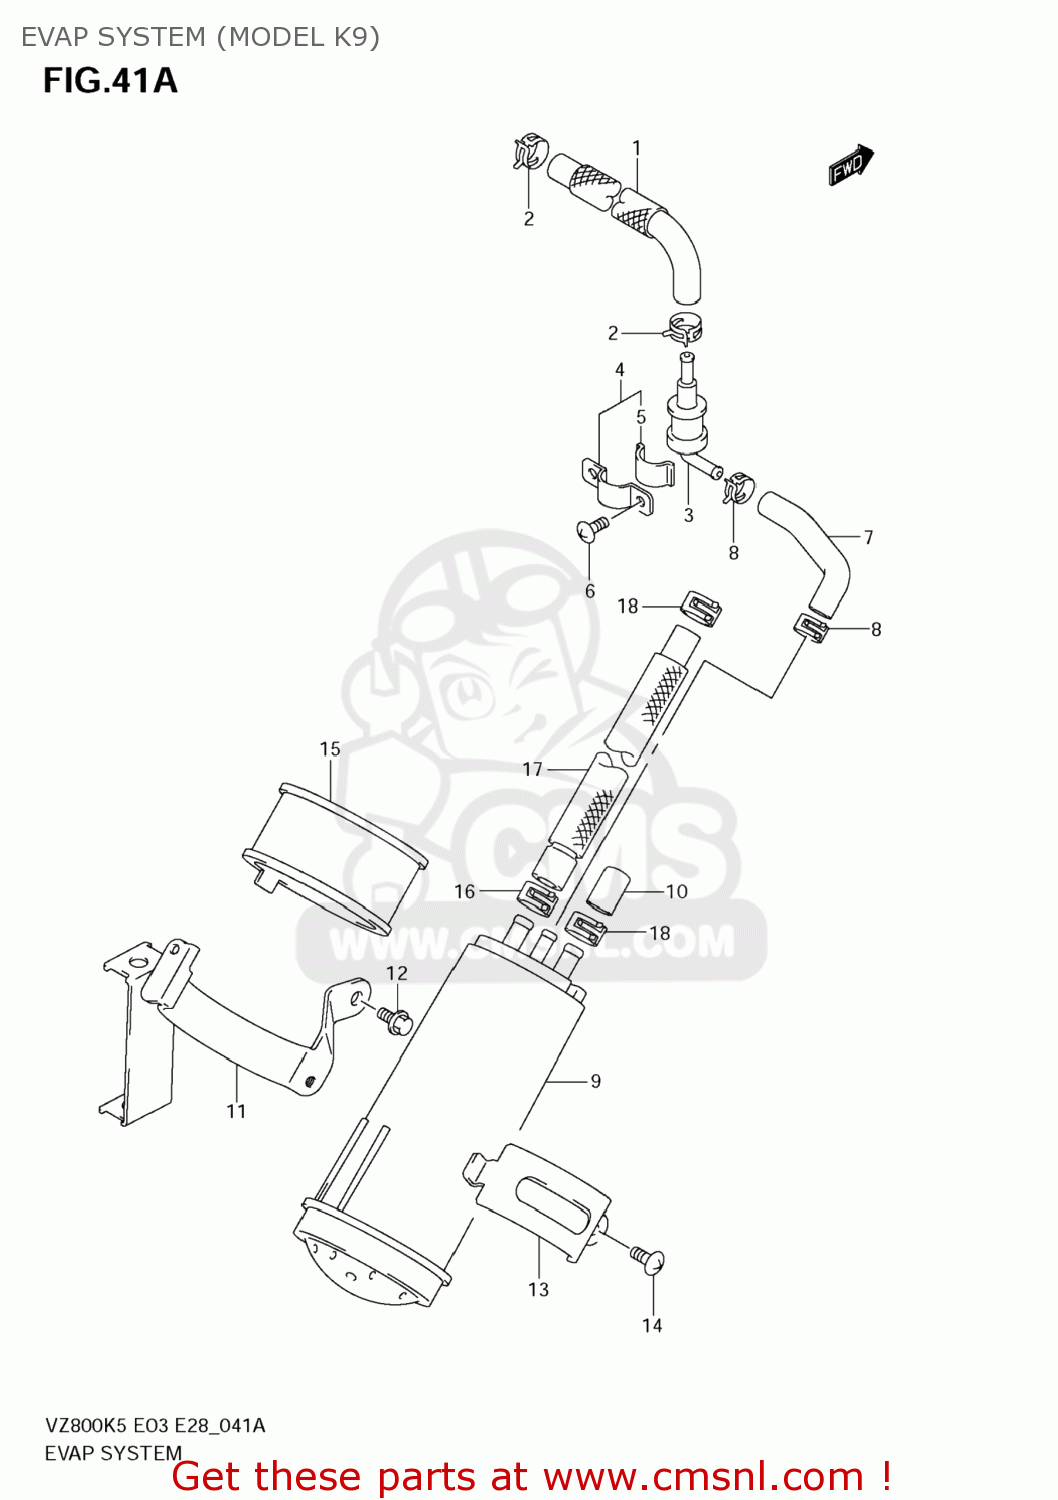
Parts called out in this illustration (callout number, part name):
1	HOSE,TANK & BREATHER VALVE
2	CLIP
3	VALVE,FUEL TANK BREATHER
4	PLATE,FUEL TANK BREATHER NO.2
5	CUSHION
6	SCREW
7	HOSE,BREATHER VALVE & CANISTER
8	CLIP
9	CANISTER SET
10	CAP,OD:11.5
11	BRACKET,FI CONTROL UNIT
12	SCREW(6X12)
13	HOLDER,CANISTER
14	SCREW
15	CUSHION,CANISTER
16	CLIP
17	HOSE,CSTR PURGE
18	CLIP
